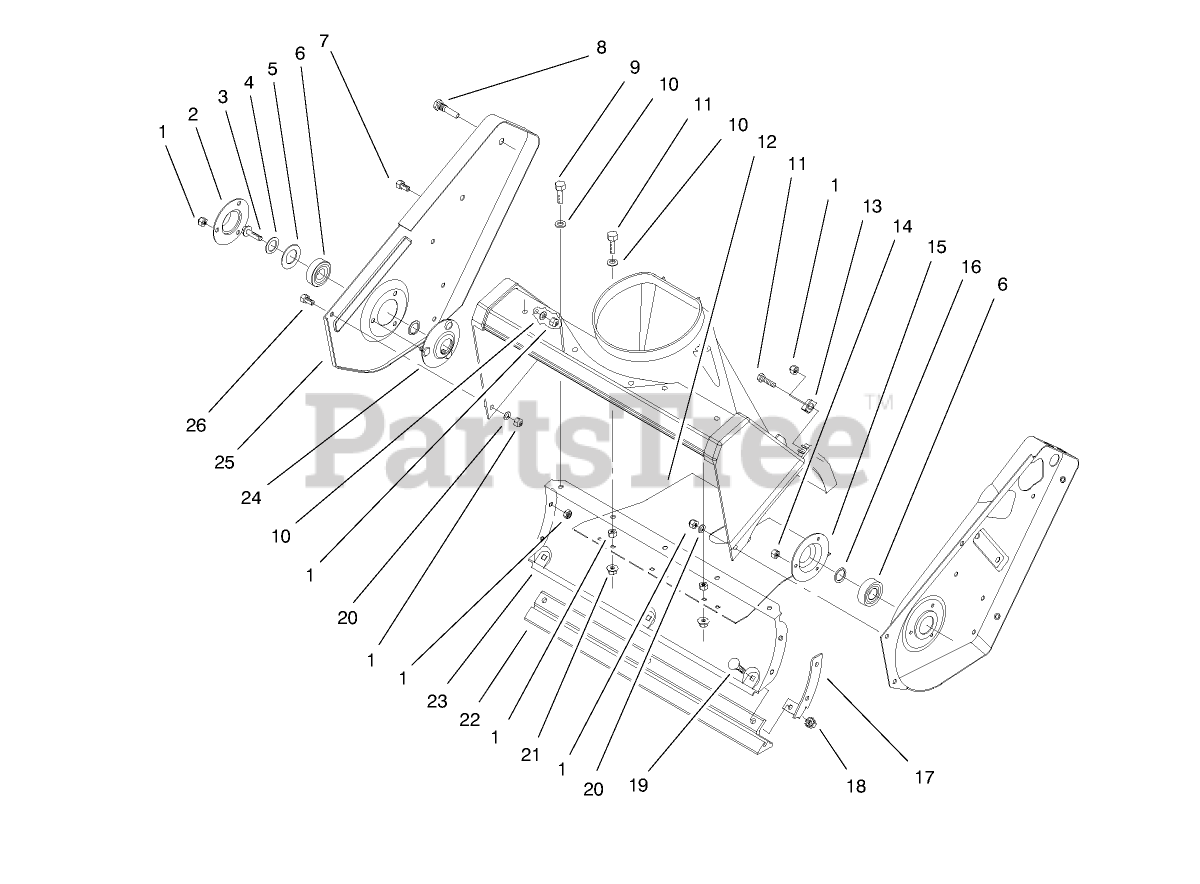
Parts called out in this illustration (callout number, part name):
1	NUT-LOCK, NI
3	SCREW-HHF
4	WASHER-FLAT
5	WASHER-RUBBER
6	BEARING-BALL
7	SCREW-HH
8	PIN-ROTOR
9	SCREW-HH
10	WASHER-FLAT
11	SCREW-HH
12	COVER-BOTTOM
13	BRACKET-HOUSING
14	NUT-LOCK, NI
15	FLANGE-BEARING
16	WASHER-THRUST
17	BRACKET-HOUSING, LOWER
18	NUT-KEPS
19	SCREW-CARR
20	WASHER
21	NUT-LOCK, HHF
22	SCRAPER
24	FLANGE-BEARING
26	SCREW-HWH
